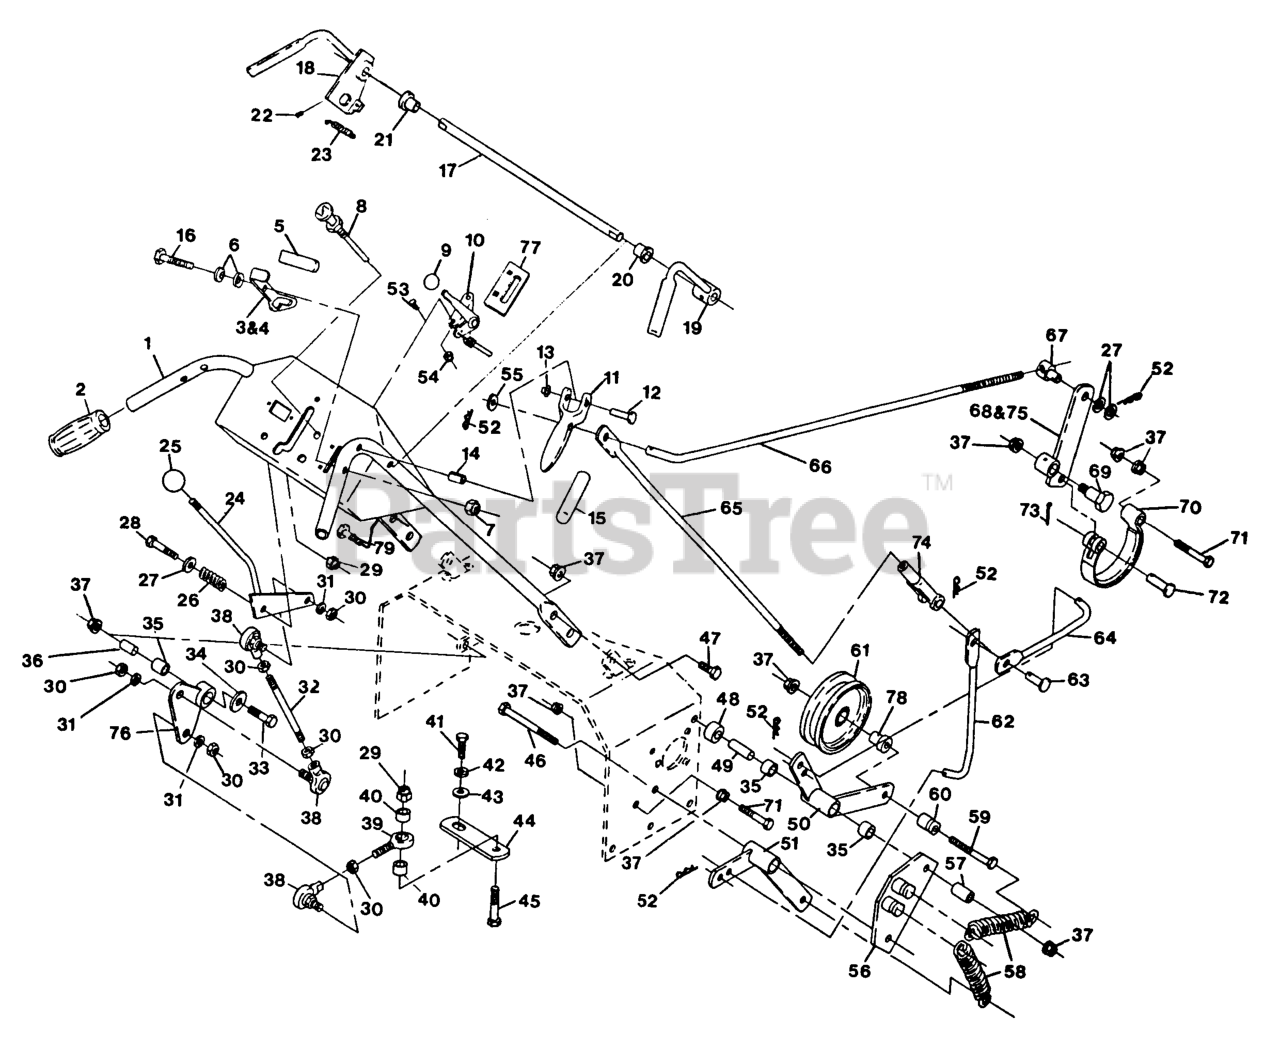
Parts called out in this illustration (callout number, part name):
5	GRIP-LATCH
6	WASHER-SPRING
8	CONTROL-CHOKE
9	KNOB-BALL
12	PIN-LEVER, DRIVE
13	NUT-PUSH
14	PIN-ROLL
15	GRIP-LEVER, DRIVE
17	ROD,CONNECTING
20	BUSHING-NYLON
21	BUSHING,FLANGED
22	SCREW-SET
23	SPRING-EXTENSION
25	KNOB-BALL
31	WASHER-LOCK
35	SLEEVE-BEARING
38	BALLJOINT
40	SPACER-PLATED
42	WASHER-LOCK
49	BUSHING-PIVOT, IDLER
52	PIN-COTTER
53	BOLT-CARR
58	SPRING-EXTENSION
60	ANCHOR-SPRING PLTD
63	PIN-CLEVIS
66	LINKAGE,BRAKE
67	SWIVEL,SHORT ADJUSTING
69	BOLT-SHOULDER
74	YOKE-ADJUSTABLE
78	BUSHING-IDLER
